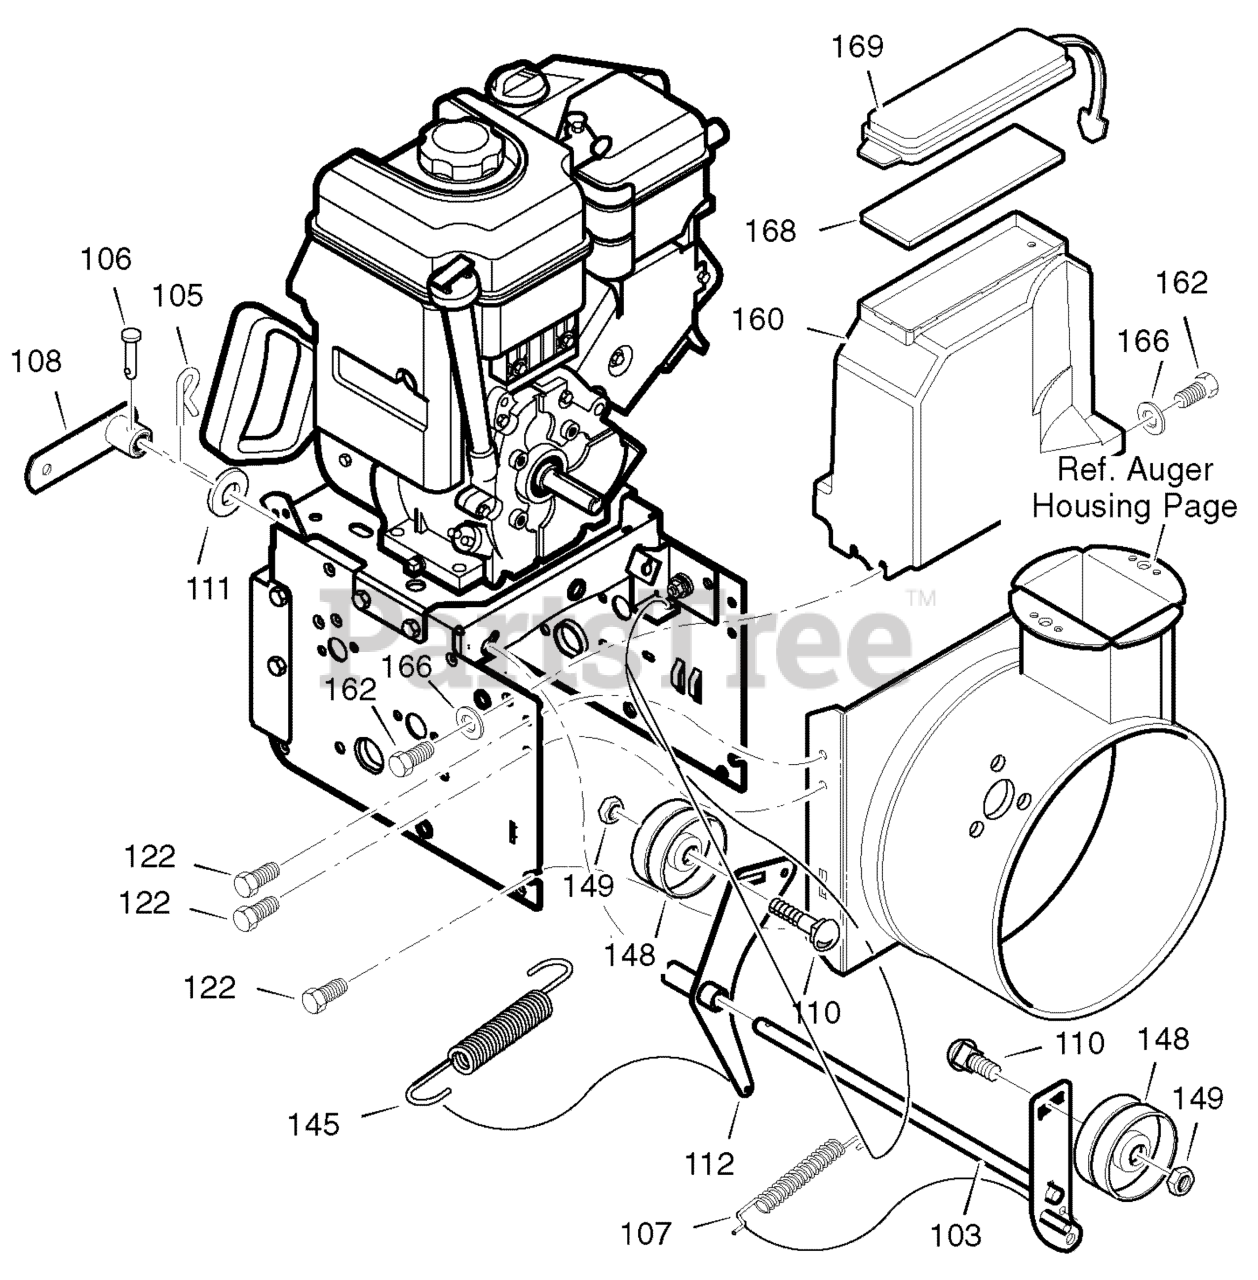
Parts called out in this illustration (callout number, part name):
103	YZ ASSY, AUGER IDLER
105	PIN, HAIR
106	PIN, CLEVIS 3/16" DIA
107	SPRING, TENSION
108	YZ SPRING ATTACHMENT
110	BOLT, 3/8-16X1.25
111	WASHER, FLAT
112	YZ BRACKET, IDLER
122	SCREW, 5/16-18 X .50
145	SPRING, CLUTCH
148	PULLEY, IDLER
149	NUT, JAM 3/8-16
160	COVER, BELT
162	SCREW, 1/4-20 X .63
166	WASHER, FLAT
168	PAD, FOAM
